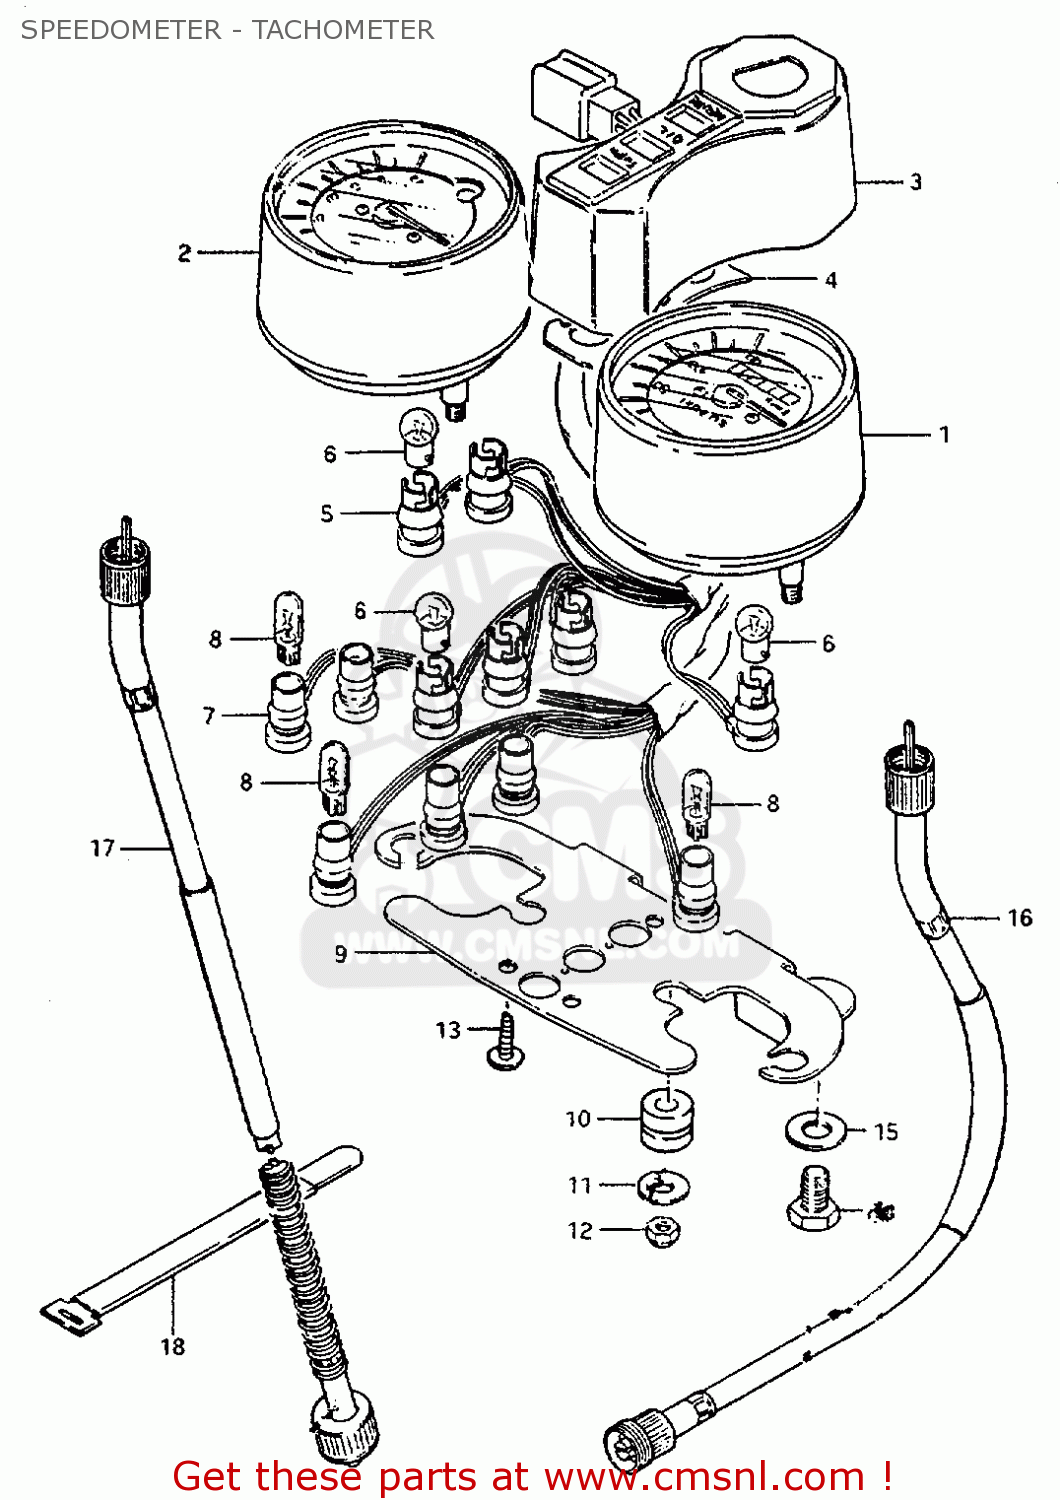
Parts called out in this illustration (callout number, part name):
1	SPEEDOMETER (MILE & KILO)
2	TACHOMETER
3	BOX, PILOT BULB
4	COVER, PILOT BOX
5	SOCKET
6	BULB(6V/3W)
7	SOCKET
8	BULB(6V,3W)
9	BRACKET
10	CUSHION,METER
11	WASHER (5.5X16X1.2)
12	NUT
13	SCREW
14	BOLT 8X12
15	WASHER
16	CABLE, SPEEDOMETER
17	CABLE ASSY,TACHOMETER
18	CLAMP
